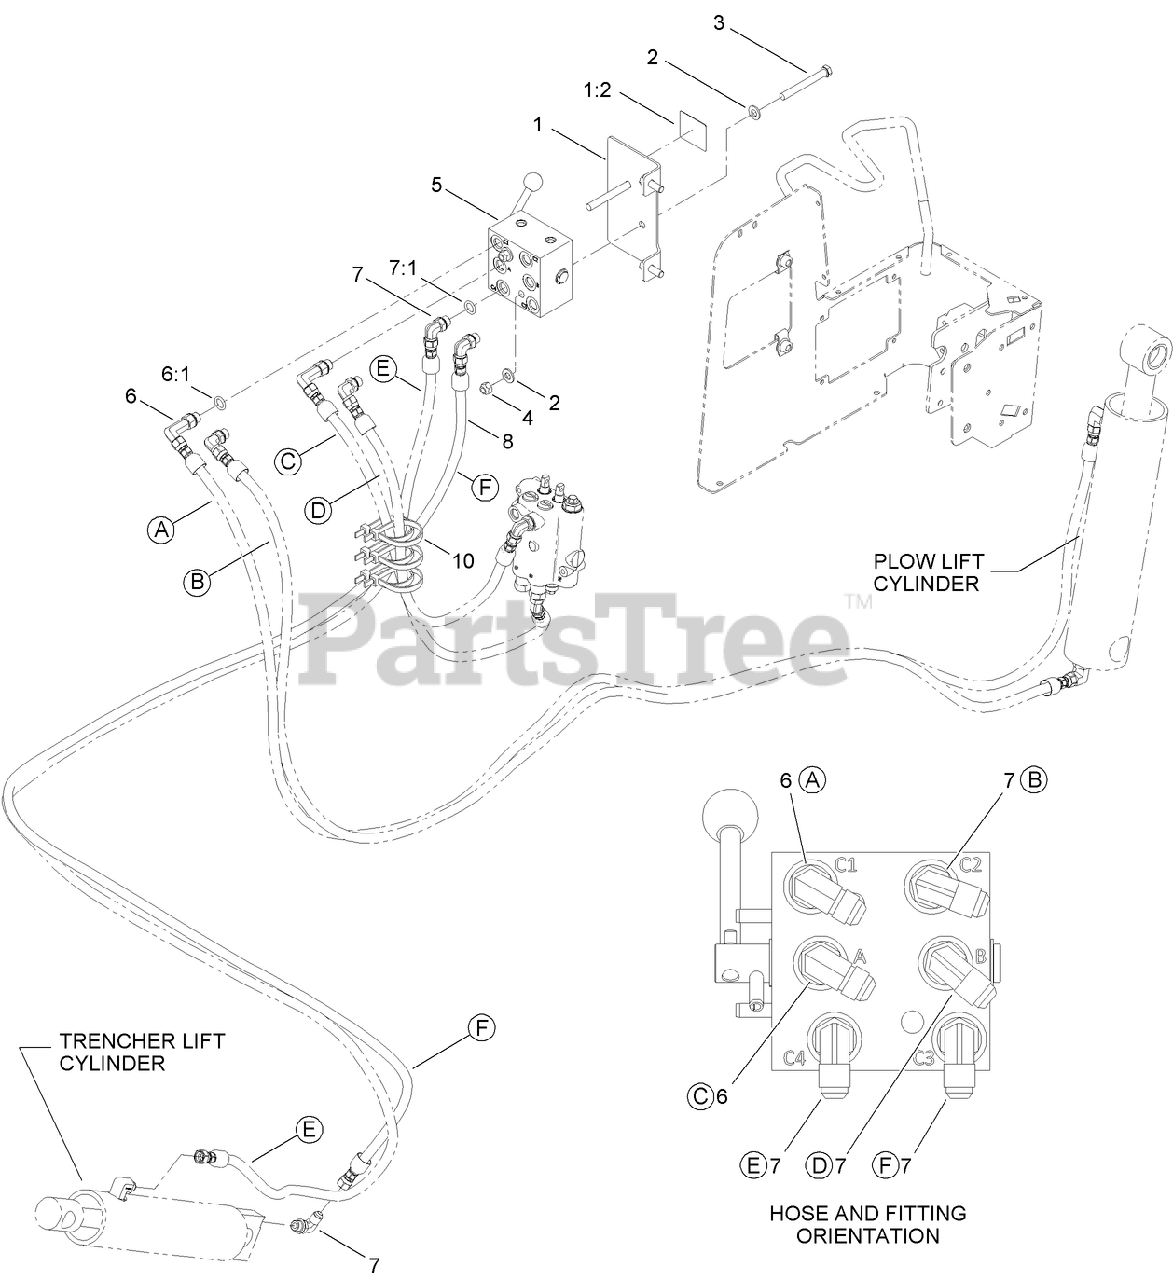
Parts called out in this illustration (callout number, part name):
1	VALVE SELECTOR BRACKET ASM
1:2	DECAL-ATTACHMENT SELECTOR
2	WASHER-FLAT
4	NUT-HEX
5	CONTROL SELECTOR VALVE ASM
6	FITTING-ADAPTOR, 90 DEG
6:1	O-RING
7	FITTING-ELBOW, 90 DEG
7:1	O-RING
8	HOSE ASM
10	TIE-CABLE
